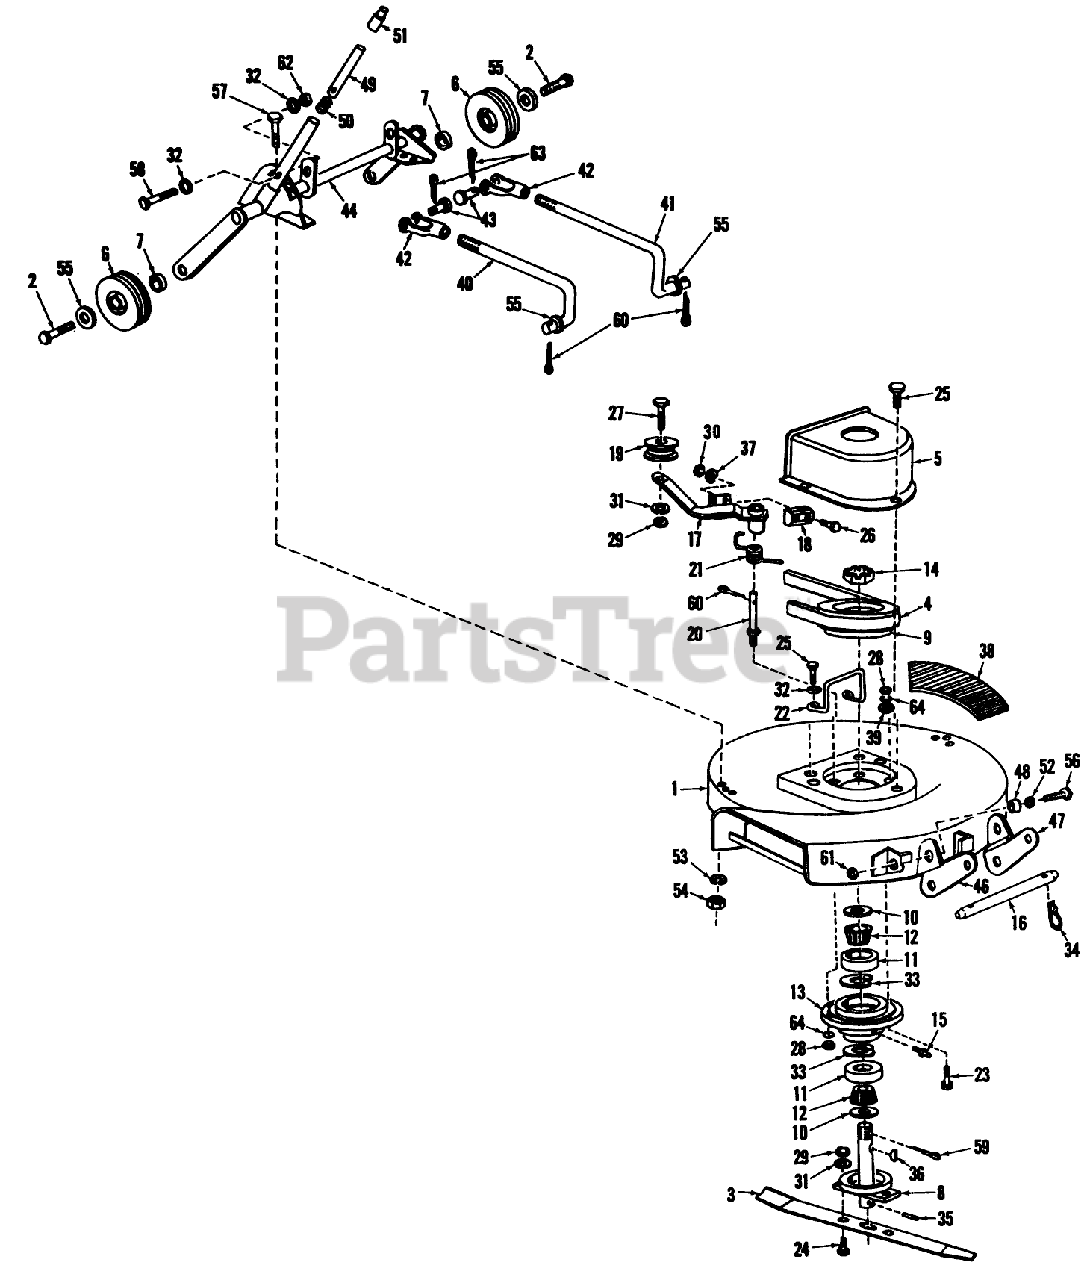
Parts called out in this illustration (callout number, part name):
1	Cutter Housing Assembly
2	Wheel Bolt
4	V-Belt-Blade Drive
5	Belt Housing
7	Wheel Spacer
8	Spindle Assembly
9	Pulley-Blade Spindle
10	Nilos Seal
11	Bearing Cups
12	Bearing Cones
13	Spindle Housing
15	Grease Fitting
16	Hanger Pin
17	Brake Arm Assembly
18	Brake Shoe
20	Brake Mounting Stud
21	Torque Spring
22	Belt Finger
23	5/16-18 x 7/8 Hex Hd. Capscrew
24	3/8-16 x 1 Hex Hd. Capscrew-H.T.
25	1/4-20 x 1/2 Hex Hd. Capscrew-Pl.
26	No. 10-24 x 5/8 Socket Hd. Capscrew
27	3/8-16 x 1 3/4 Hex Hd. Capscrew
28	5/16-18 Hex Lock Nut
29	3/8-16 Hex Nut
30	No. 10-24 Hex Nut
31	3/8 Lockwashers
32	1/4 Flat Washer
33	Retaining Rings
34	Spring Clip
35	5/32 x 1 1/2 Roll Pin
36	3/16 x 3/4 Woodruff Key
37	No. 10 External Shakeproof Lockwashers
38	Foot Pad
39	5/16 Flat Washers
40	Hanger Rod-R.H.
41	Hanger Rod-L.H.
43	Clevis Pins
44	Wheel Support Assembly
46	Bellcrank-R.H.
47	Bellcrank-L.H.
51	Rubber Tip
52	5/16 Flat Washer
53	5/16 Lockwasher
54	5/16-18 Hex Nut
55	1/2 SAE Flat Washer-Pl.
56	3/8-16 x 7/8 Hex Hd. Capscrew
57	5/16-18 x 3/4 Hex. Hd. Capscrew
58	1/4-20 x 2 Hex Hd. Capscrew-Pl.
59	1/8 x 1 1/2 Cotter Pin-Pl.
60	1/8 x 3/4 Cotter Pin-Pl.
61	3/8-16 Hex Locknut-Pl.
62	1/4-20 Hex Locknut-Pl.
63	1/8 x 1 Cotter Pin-Pl.
64	1/4 Lockwasher-Pl.
